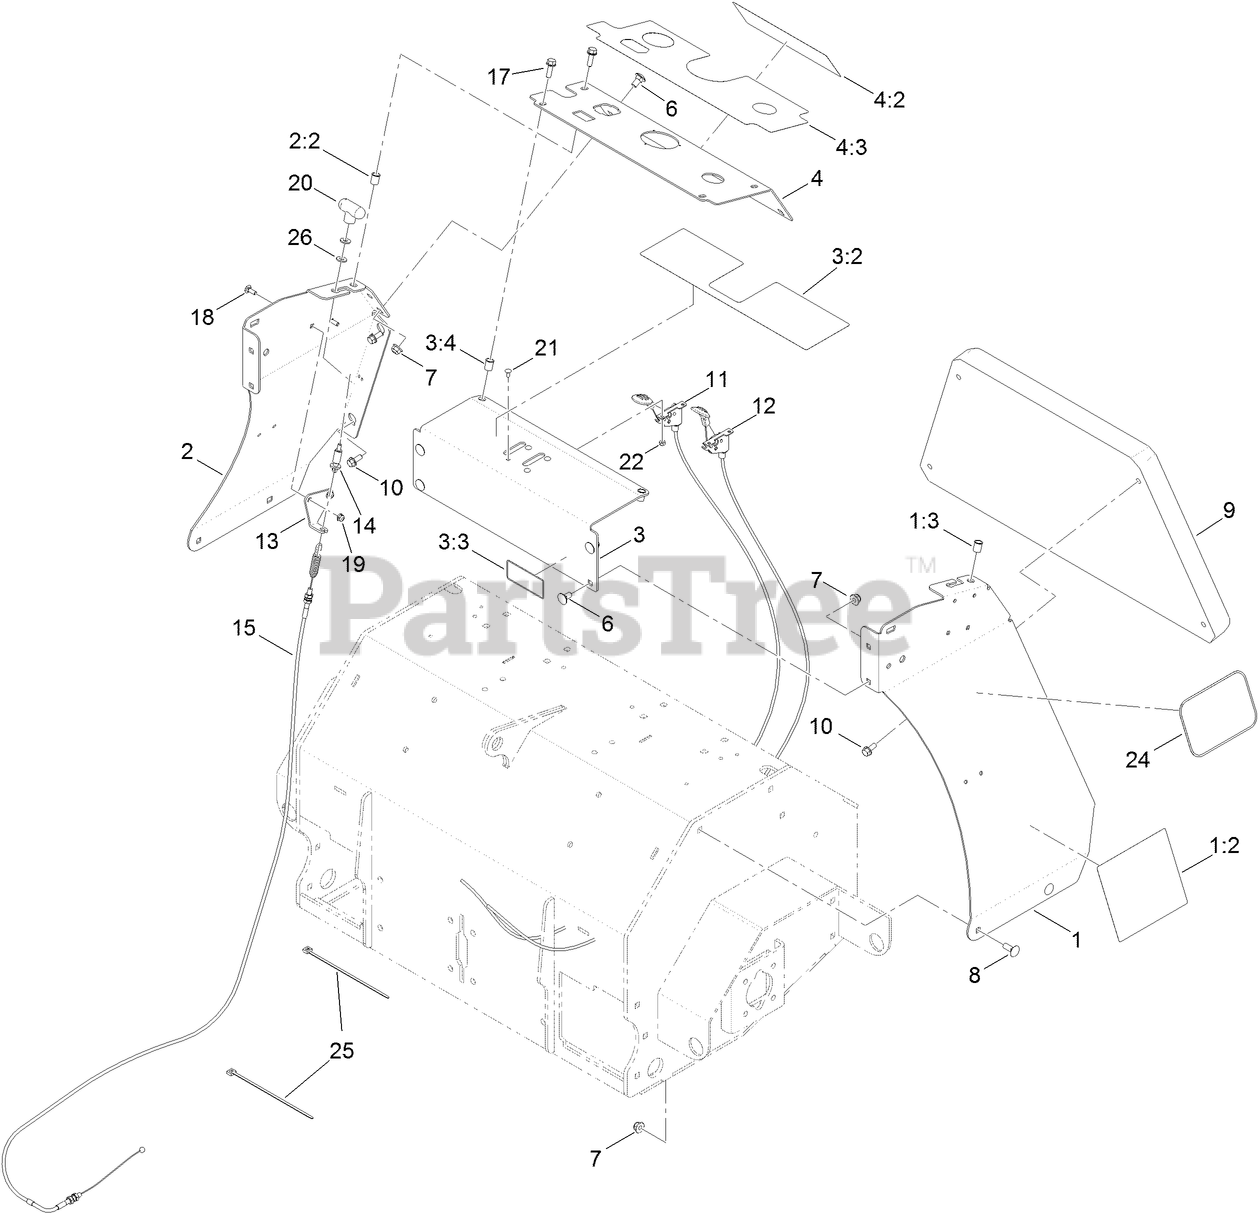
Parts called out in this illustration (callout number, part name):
1	LH SIDE PANEL ASM
1:2	DECAL-SERVICE AID CE
1:3	NUT-INSERT
2	RH SIDE PANEL ASM
2:2	NUT-INSERT
3	PLATE ASM
3:2	DECAL-WARNING, CONTROL PANEL
3:3	DECAL-WARNING, TINES
3:4	NUT-INSERT
4	CONSOLE ASM
4:2	DECAL-DANGER
4:3	DECAL-DANGER, CONTROL PANEL
6	SCREW-CARR
7	NUT-HF, NI
8	BOLT-CARR
9	CUSHION-BLACK
10	SCREW-HHF
11	CONTROL-CHOKE
12	CONTROL-THROTTLE
13	BRACKET-CABLE, BRAKE
14	LINK-CABLE, BRAKE
15	CABLE-BRAKE
17	SCREW-HHF
18	BOLT-CARR
19	NUT-HF
20	KNOB-TEE
21	BOLT-CARR
22	NUT-LOCK, NI
24	DECAL
25	TIE-PLASTIC
26	WASHER-FLAT
